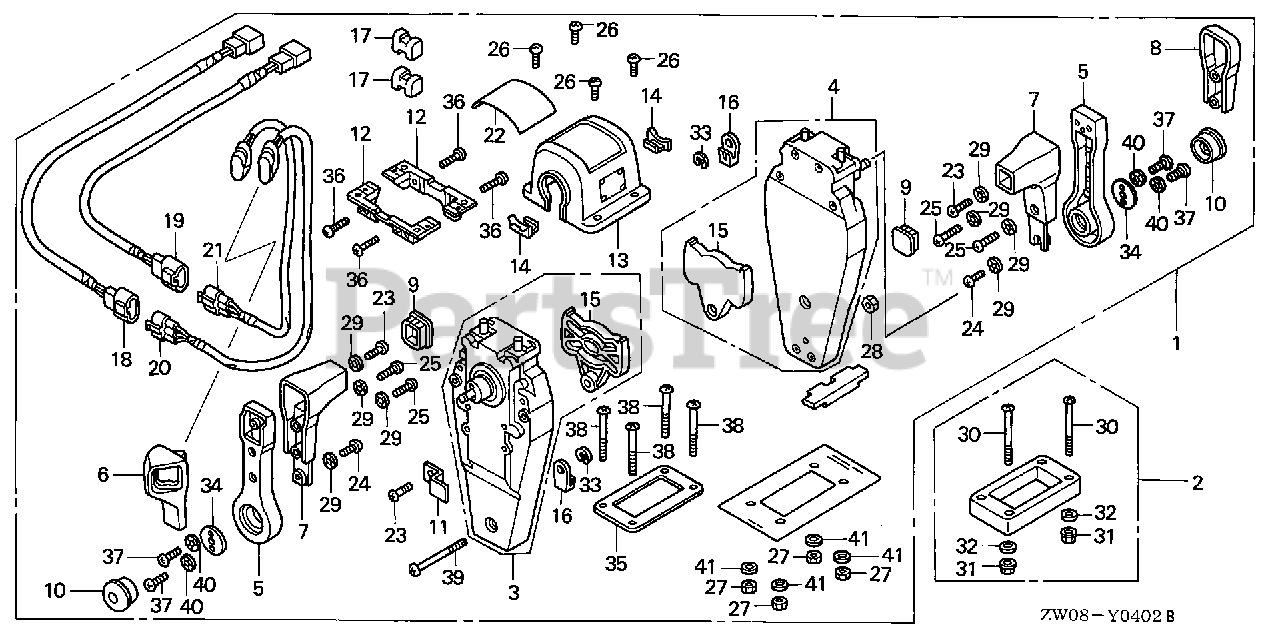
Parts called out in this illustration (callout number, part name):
1	BOX KIT, R. REMOTE CONTROL (TOP MOUNT DUAL)
2	SPACER KIT, REMOTE CONTROL BOX (TOP MOUNT DUAL)
3	HOUSING ASSY., L. (INNER) (TOP MOUNT)
4	HOUSING ASSY., R. (INNER) (TOP MOUNT)
5	HANDLE, REMOTE CONTROL
6	COVER, L. GRIP
7	GRIP, REMOTE CONTROL HANDLE
8	COVER, DUAL GRIP
9	CAP, GRIP
10	BUTTON, THROTTLE
11	PLATE, CABLE CLAMP
12	BRACKET, REMOTE CONTROL HOUSING
13	HOUSING, DUAL REMOTE CONTROL BOX
14	HOUSING, LEAD
15	PLATE, DWELL
16	TERMINAL, CABLE
17	SPACER, CABLE CLAMP
18	SUB-HARNESS ASSY., POWER TRIM-TILT (A)
19	SUB-HARNESS ASSY., POWER TRIM-TILT (B)
20	SWITCH ASSY., POWER TRIM-TILT (A)
21	SWITCH ASSY., POWER TRIM-TILT
22	MARK, REMOTE CONTROL (DUAL)
23	SCREW, PAN (5X16)
24	SCREW, PAN (5X10)
25	SCREW, PAN (5X20)
26	SCREW, PAN (4X10)
27	NUT, HEX. (5MM)
28	NUT, HEX. (5MM)
29	WASHER, LOCK (5MM)
30	SCREW, PAN (5X65)
31	NUT, FLANGE (5MM)
32	WASHER, PLAIN (5MM)
33	E-RING (6MM)
34	PLATE, HANDLE
35	GASKET, DUAL
36	SCREW, PAN (5X18)
37	SCREW, PAN (6X18)
38	SCREW, PAN (5X40)
39	SCREW, PAN (5X55)
40	WASHER, LOCK (6MM)
41	WASHER, PLAIN (5MM)
